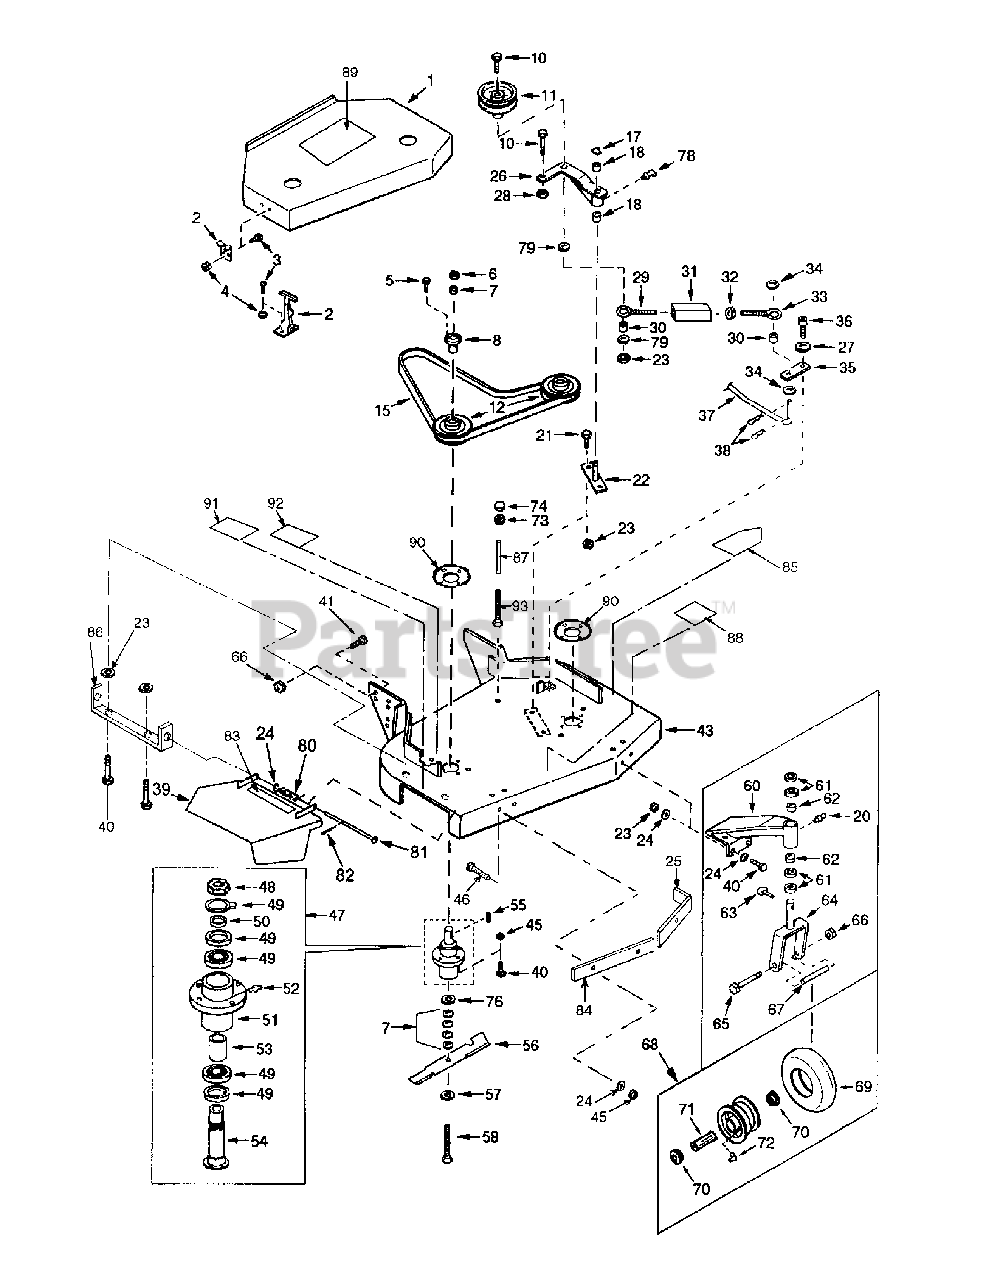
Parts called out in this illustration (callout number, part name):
1	32" Deck Cover
2	Rubber Latch
3	Machine Screw, 10-24 x 1/2 Round Hd.
4	Hex Nut, 10-24 Nylock
5	Cap Screw, 1/4-20 x 3/4 Hex Hd.
6	Hex Nut, 5/8-11
7	Blade Spacer
8	Pulley Bushing
10	Cap Screw, 3/8-16 x 2-1/2 Hex Hd.
11	Idler, Deck Take-up
12	Deck Pulley
15	Drive Belt (32" Deck)
17	E-Ring, External
18	Sintered Bushing
20	Grease Fitting, 1/4-28, Taper, Str.
21	Cap Screw, 3/8-16 x 1 Hex Hd.
22	Idler Pivot
23	Hex Nut, 3/8-16 Nylock
24	Flat Washer, 3/8, Small O.D.
25	Bumper Deck 32"
26	Pivot Arm, Deck Take-up Idler Pulley
27	Shim Washer, 3/4 x 1/2 x 1/16
28	Hex Nut, 3/8-16
29	Eyebolt, L.H.
30	Sleeve
31	Turnbuckle (32" Deck)
32	Hex Nut, 5/16-18
33	Eyebolt, R.H.
34	Flat Washer, 3/8, Large O.D.
35	Clutch Link
36	Shoulder Bolt, 1/2 X 3/8
37	Rod, Blade Clutch
38	Hairpin, 3/8-7/16
39	Discharge Chute
40	Cap Screw, 3/8-16 x 1-1/4 Hex Hd.
41	Cap Screw, 1/2-13 x 1-1/4 Hex Hd.
43	32" Cutter Deck
45	Hex Nut, 3/8-16 Stover
46	Bolt, Carriage 3/8"
47	Spindle Assembly
48	Hex Nut, 1-1/8-12 UNF, Jam
49	Kit, Spindle Repair
50	Seal Spacer
51	Spindle Housing
52	Grease Fitting
53	Internal Spacer
54	Spindle
55	Key, 1/4 x 1/4 x 2
56	Rotary Blade, 16-1/2"
57	Flat Washer, 5/8
58	Cap Screw, 5/8-11 x 9-1/2 Hex Hd.
60	Caster Bracket
61	Caster Spacer
62	Bushing, Caster Bracket
63	Lynch Pin, 7/16 x 1-7/8
64	Caster Yoke
65	Cap Screw, 1/2-13 x 5-1/2 Hex Hd.
66	Hex Nut, 1/2-13 Nylock
67	Sleeve, Caster Wheel Bearing
68	Caster Wheel Assembly
69	Tire, Caster Wheel
70	Bearing Retainer, Caster Wheel
71	Roller Bearing, Caster Wheel
72	Grease Fitting, 1/4-28, 45 degree
73	Cap Screw
74	Protective Cap
76	Flat Washer, 1-1/2 x 5/8 x .055
78	Grease Fitting
79	Flat Washer, 5/16 USS
80	Torsion Spring
81	Deflector Pivot Pin Ass’y
82	Cotter Pin, 1/8 x 1
83	Decal, "Width of Cut"
84	Bumper, Deck
85	Decal, Danger
86	Bracket, Deflector
87	Spacer, Belt Guard
88	Decal, "Warning Shield Missing"
89	Label, Command Deck MTD Pro 32
90	Plate, Spindle Backing
91	Decal, Rotating Blade Danger
92	Decal, Warning Safety Procedure
